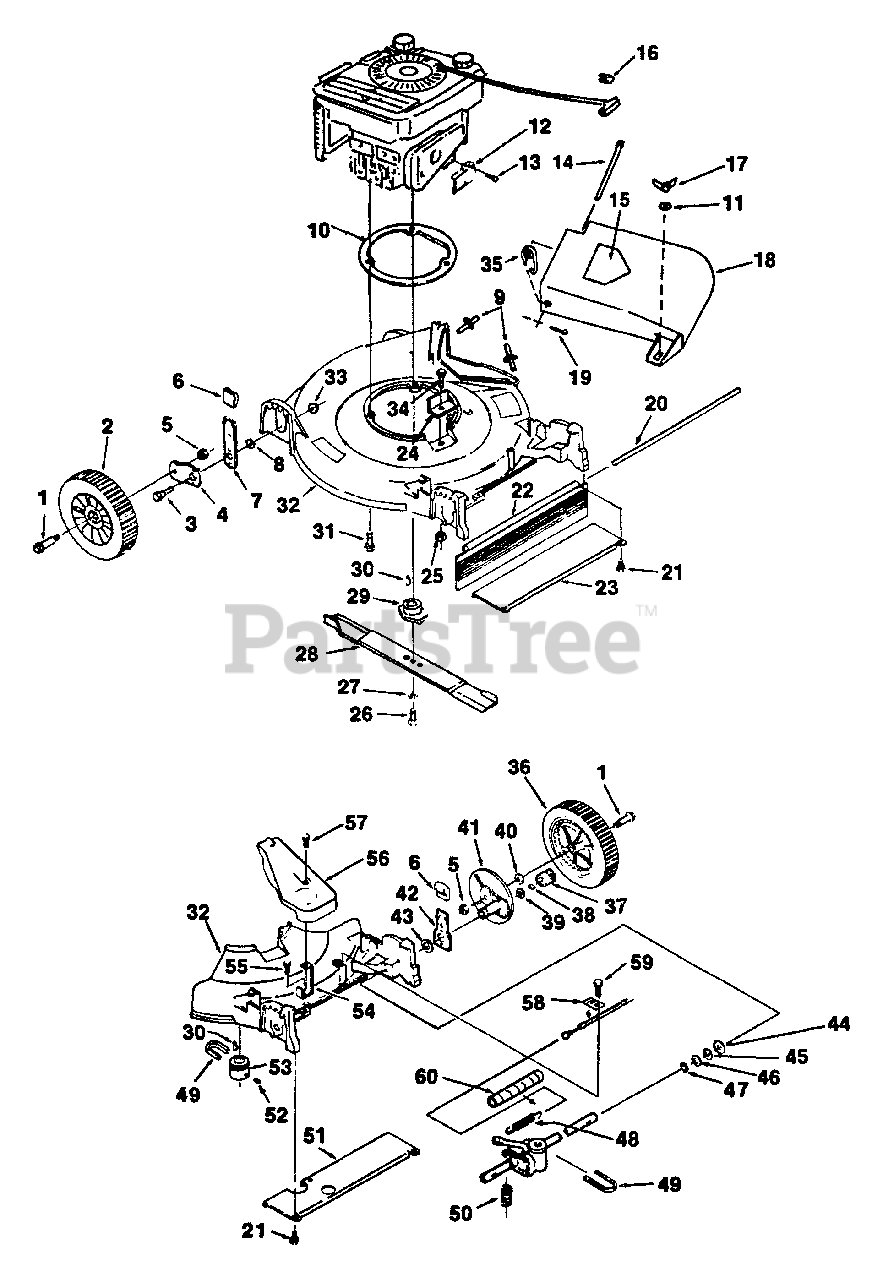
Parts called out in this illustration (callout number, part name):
1	AXLE - ASSY
2	WHEEL ASSY
3	BOLT - 5/16×18
4	ARM - WHEEL ADJUSTING
5	NUT - 3/8-24
6	KNOB
7	INDEXING SPRING & PIN ASSY
8	SPACER
9	STUD
10	RING - ENGINE
11	WASHER - 1/4"
12	DEFLECTOR
13	SCREW - 8-32×3/8" - HEX CAP
14	PIN - HINGE
15	LABEL - WARNING
16	ROPE STOP
17	WINGNUT
18	DISCHARGE COVER
19	PIN - COTTER
20	ROD
21	SCREW - 1/4-20×3/4" -- HEX CAP
22	FLAP - DRAG
23	COVER, REAR
24	COVER, BELT
25	LOCKNUT - 1/4-20
26	SCREW - 0.375×1.2" -- HEX CAP
27	WASHER, LOCK 3/8
28	BLADE, MOWER
29	ADAPTOR
30	KEY
31	SCREW 3/8"-16×1-1/2"
32	DECK
33	NUT - 5/16-18 -- FLANGE
34	SCREW - 1/4-20×1/2"
35	SPRING
36	WHEEL ASSY
37	PINION - R.H.
38	PAWL
39	WASHER, FLAT
40	WASHER, FLAT
41	DRIVE WHEEL SUPPORT ASSY
42	INDEXING SPRING & PIN ASSY
43	SPACER
44	WASHER
45	WASHER
46	WASHER
47	RING - EATON
48	SPRING
49	BELT - DRIVE
50	SPRING, COMPRESSION
51	COVER - REAR
52	SCREW, SET
53	PULLEY - DRIVE
54	BRACKET
55	SCREW - 1/4-20×9/16"
56	COVER - DRIVE
57	SCREW - 1/4-20×3/4" -- HEX HEAD
58	CLAMP
59	SCREW 1/4"×5/8
60	COVER - SPRING
